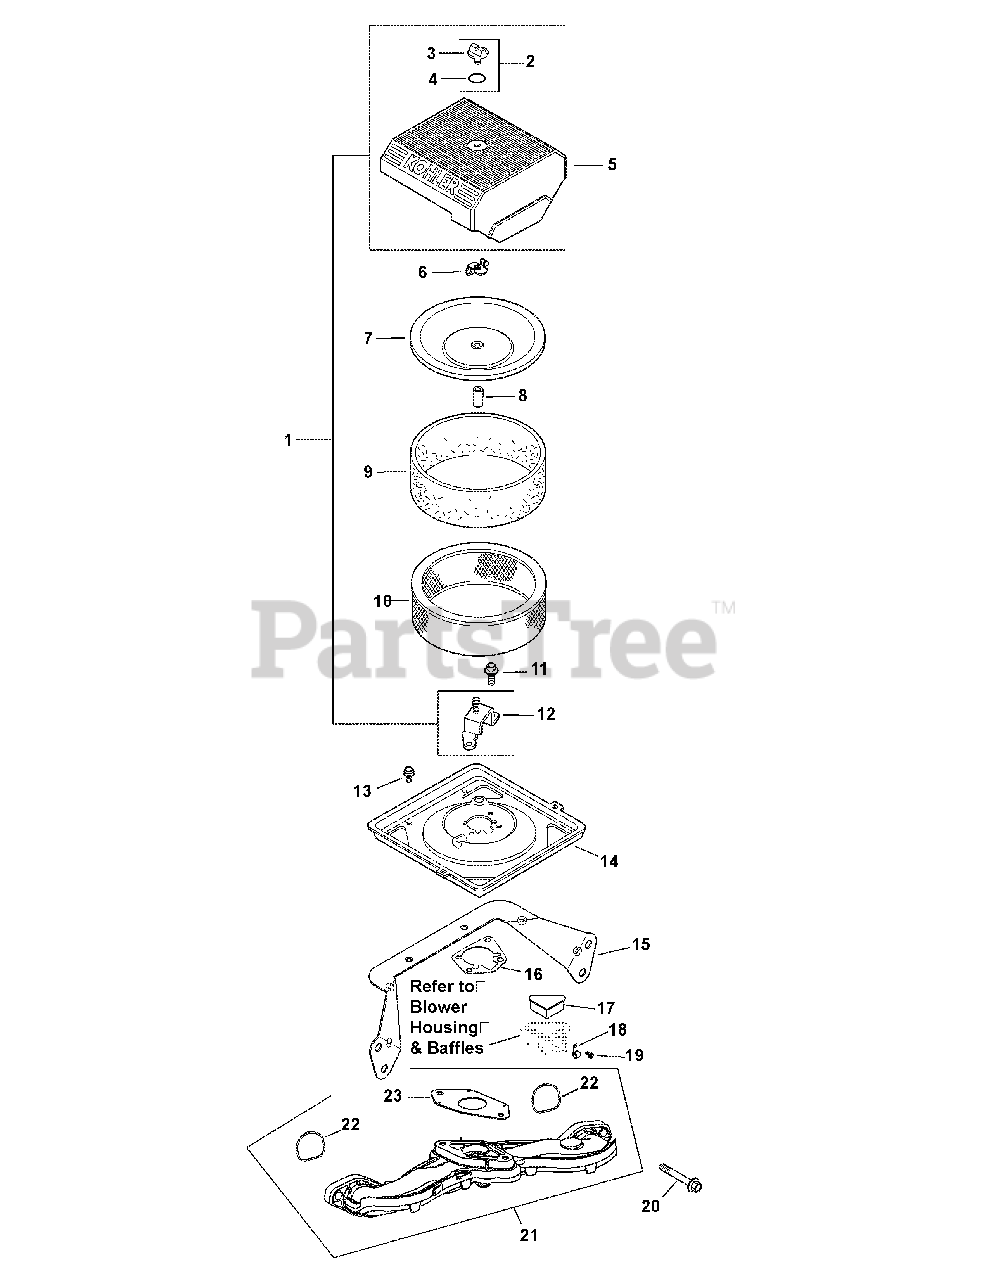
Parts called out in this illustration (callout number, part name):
1	Kit, air cleaner cover (Incl 2 5,12)
2	Kit, knob w/seal (Includes 3,4)
5	Cover, air cleaner
7	Cover, inner air cleaner
8	Seal, inner air cleaner
9	Element, precleaner
10	Element, air cleaner
11	Screw, flg thd frm M6x1.0x16
12	Bracket, air cleaner
13	Screw, flg thd frm M5x0.8x10
14	Base, air cleaner
15	Bracket, air cleaner base
16	Gasket, air cleaner base
17	Cover, blower housing
19	Screw, wsh hd tap #8-18x1/2"
20	Screw, flg M6x1.0x40
21	Manifold, intake - plastic (Includes 22 & 23)
22	O-Ring, intake port
23	Gasket, carburetor
